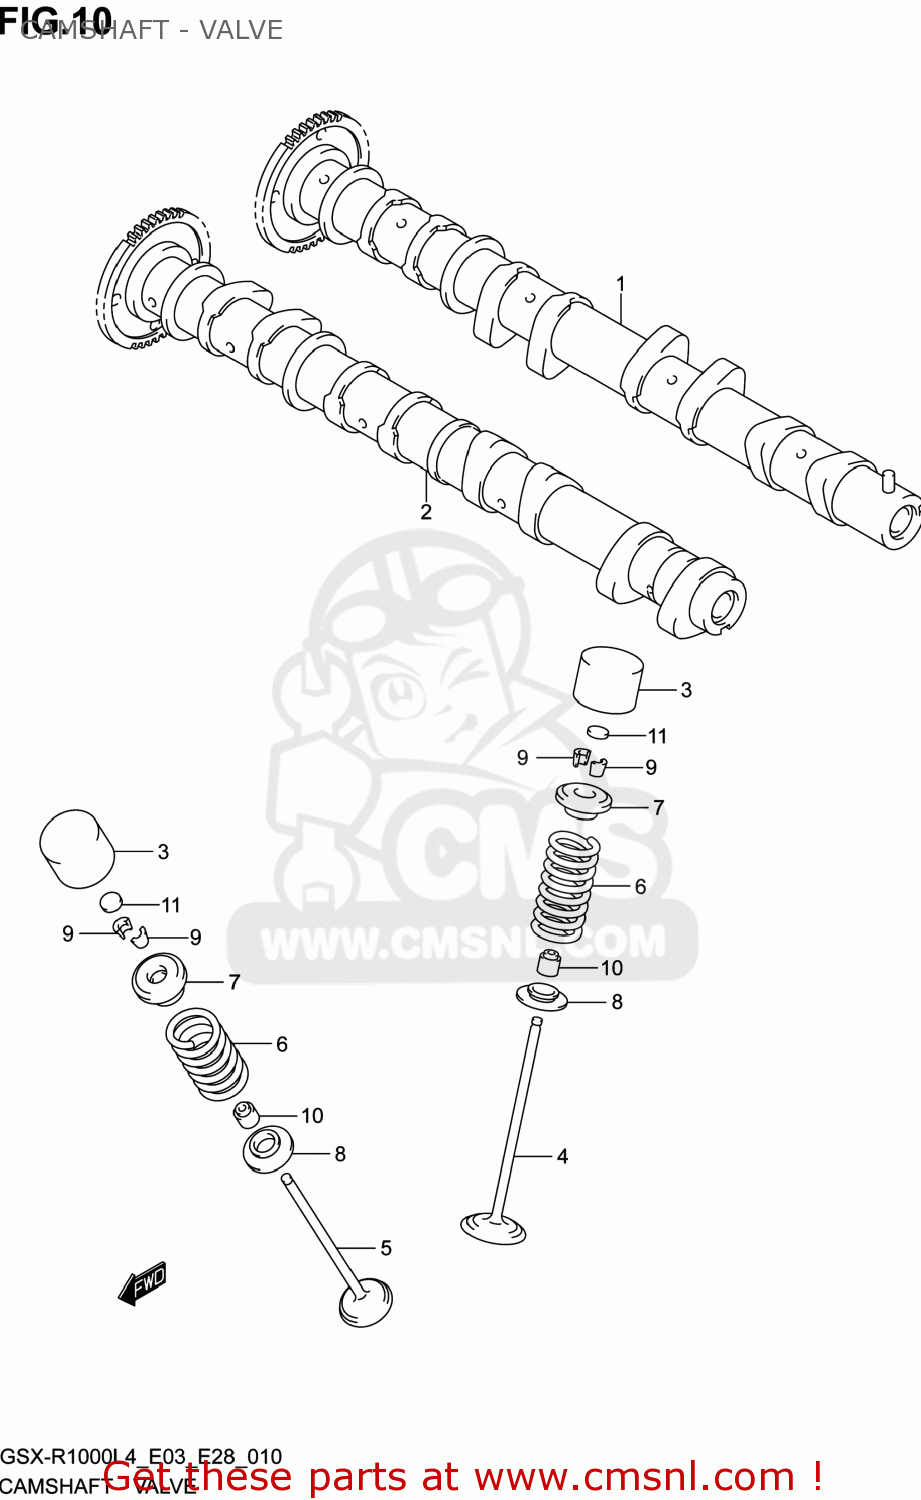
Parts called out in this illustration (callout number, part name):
1	CAMSHAFT,INTAKE
2	CAMSHAFT,EXHAUST
3	TAPPET
4	VALVE,INTAKE
5	VALVE,EXHAUST
6	SPRING SET,VALVE
7	RETAINER,VALVE SPRING
8	SEAT,VALVE SPRING
9	COTTER VALVE
10	SEAL,OIL(4.5X10X8)
11	SHIM,TAPPET
12	SHIM SET,TAPPET
13	CASE,TAPPET SHIM
